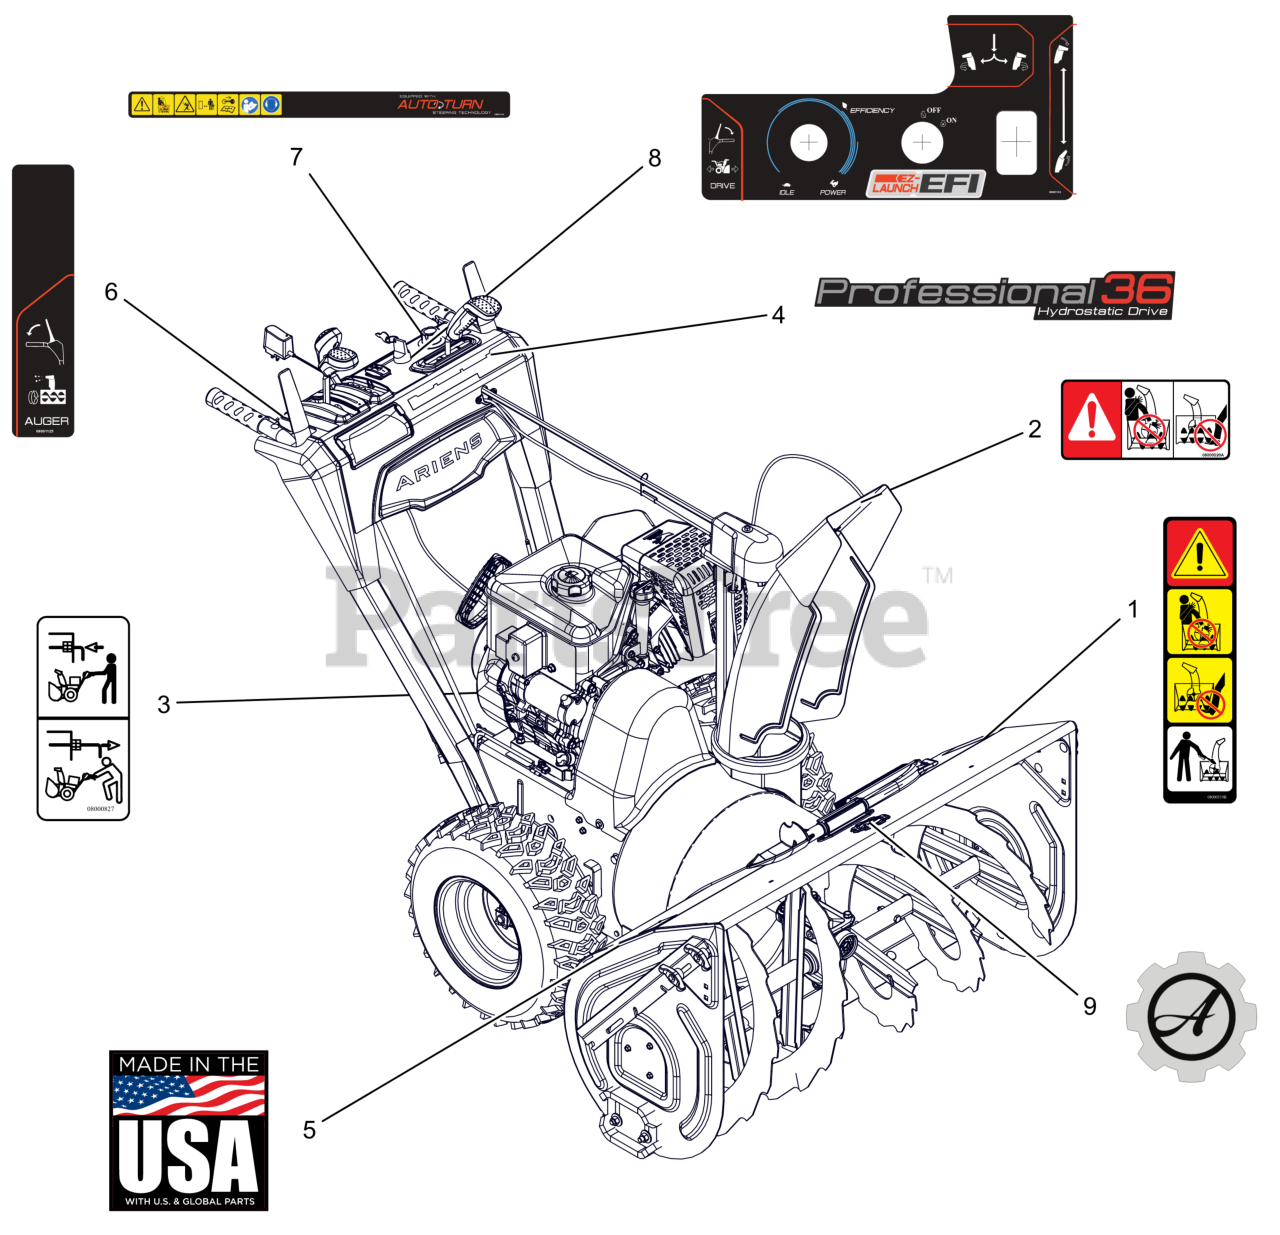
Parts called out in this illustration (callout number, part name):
1	DECAL, DANGER - ROTATING PARTS
2	DECAL, DANGER
3	DECAL, BYPASS
4	DECAL, DASH - PRO HYDRO 36
5	DECAL, MADE IN USA
6	DECAL,CONTROL-RH CONTROL
7	DECAL,DASH - SAFETY/EFI
8	DECAL, CONTROL - QT EFI W/GEL
9	DECAL, ARIENS-GEAR BADGE -THK
